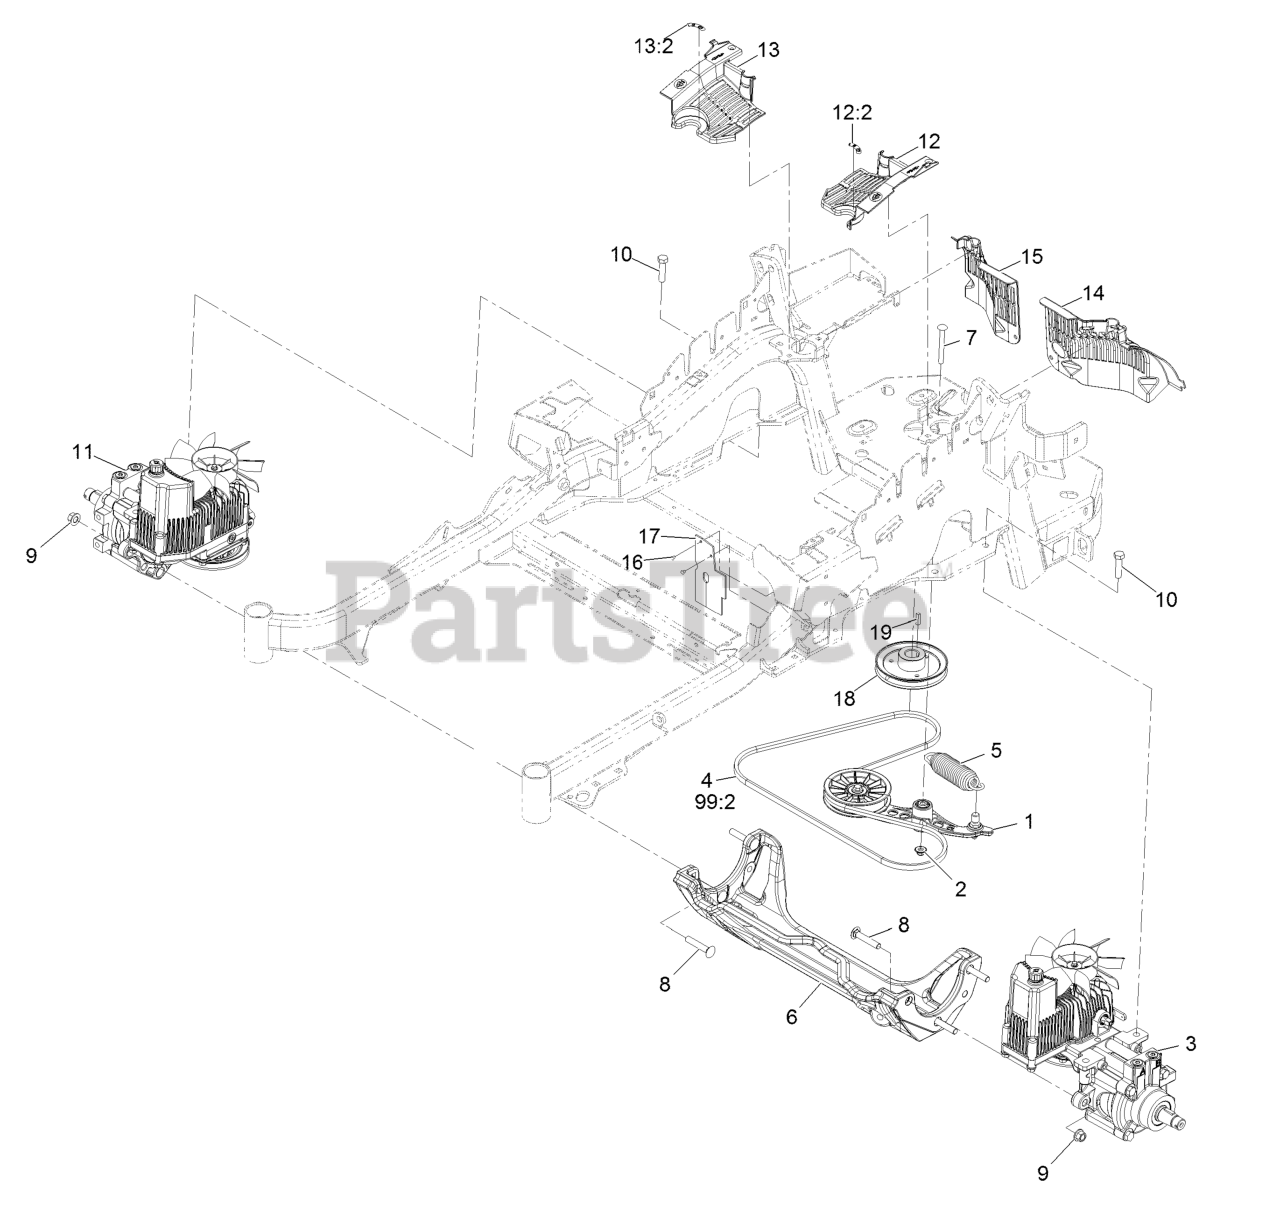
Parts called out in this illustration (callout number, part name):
1	Pump Idler ASM
2	Nut-Nyloc 3/8-16 Flg
3	LH Hydro ASM (12Cc W/ Check)
4	Belt
5	Spring-Extension
6	Cradle-Hydro
7	Bolt-Carriage Shoulder 3/8-16 X 3 1/2
8	Screw-CARR
9	Nut-Lock 1/2-13
10	Screw-HH 1/2-13 X 1 1/4
11	RH Hydro ASM (12Cc W/ Check)
12	LH Hydro Guard ASM
12:2	Decal-Oil, Hydro
13	RH Hydro Guard ASM
13:2	Decal-Oil, Hydro
14	Guard-Hydro, Rear (LH)
15	Guard-Hydro, Rear (RH)
16	Rivet 3/16 X 1/4
17	Deflector-Air Flow
18	Sheave
99	Bottle-Oil, 32Oz Hydraulic
99	Filter-Hydro
99	Bottle,Oil 1 Gallon Hydraulic
99	Kit, Hydro Service
99:1	Bottle-Oil, 32Oz Hydraulic
99:2	Belt
99:3	Filter-Hydro
